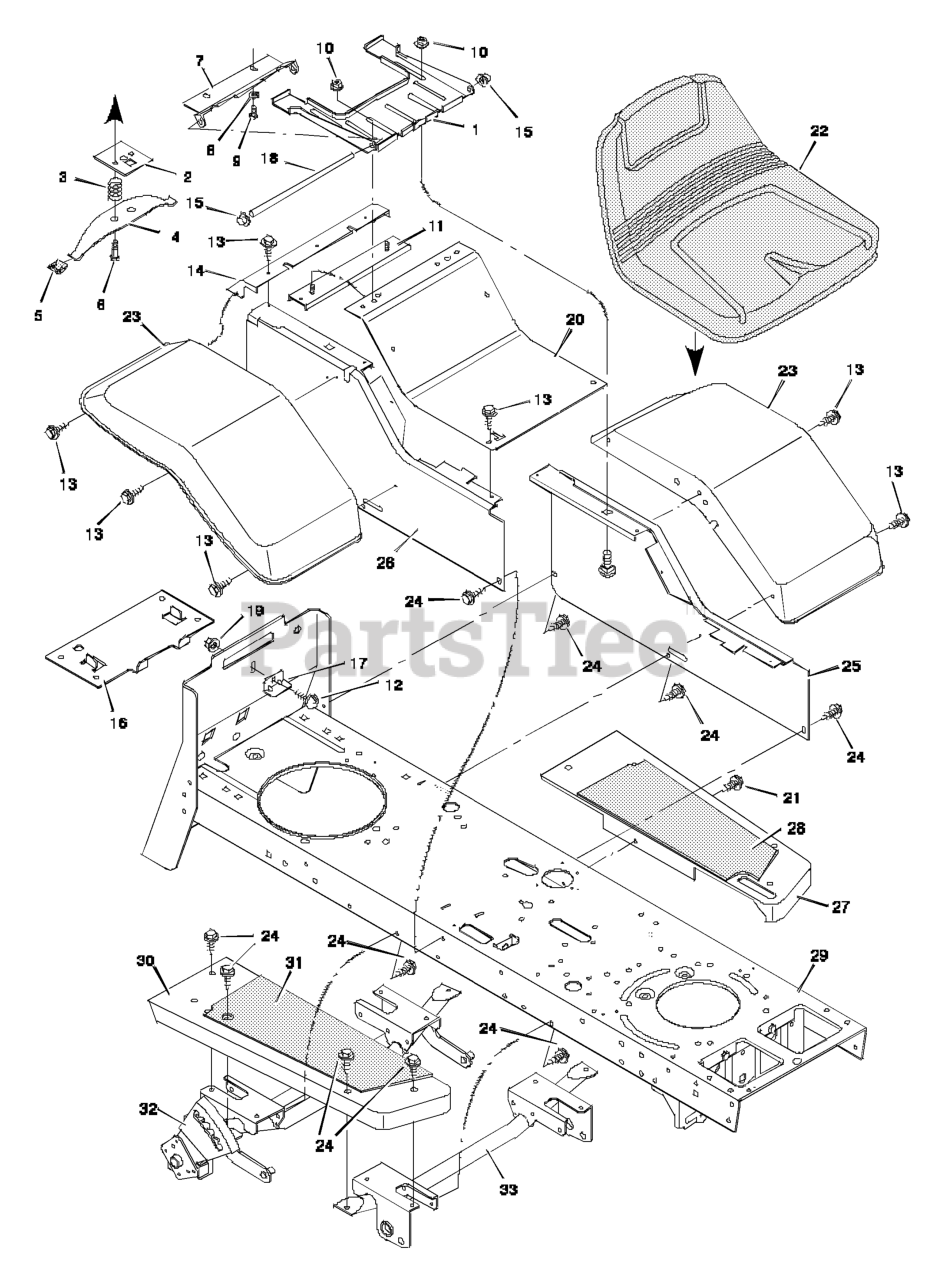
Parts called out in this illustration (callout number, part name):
1	Bracket, Seat
2	Plate Assembly, Switch
3	Spring, Compression
4	Spring, Seat
5	Glide, Spring
6	Bolt, Shoulder
7	Support, Seat
8	Lockwasher
9	Bolt, Hex
10	Locknut, Flange
11	Channel Assembly
12	Bolt, Carriage
14	Insert, Rear
15	Push On Cap
16	Support, Battery
17	Clamp, Battery
18	Rod, Pivot
19	Locknut
20	Panel, Top
21	Fastener, Panel
25	Panel, Left
26	Panel, Right
27	Running Board, Left
28	Mat, Left
29	Frame Channel
30	Running Board, Right
31	Mat, Right
32	Lifter and Support Assembly
33	Support Assembly, Front
